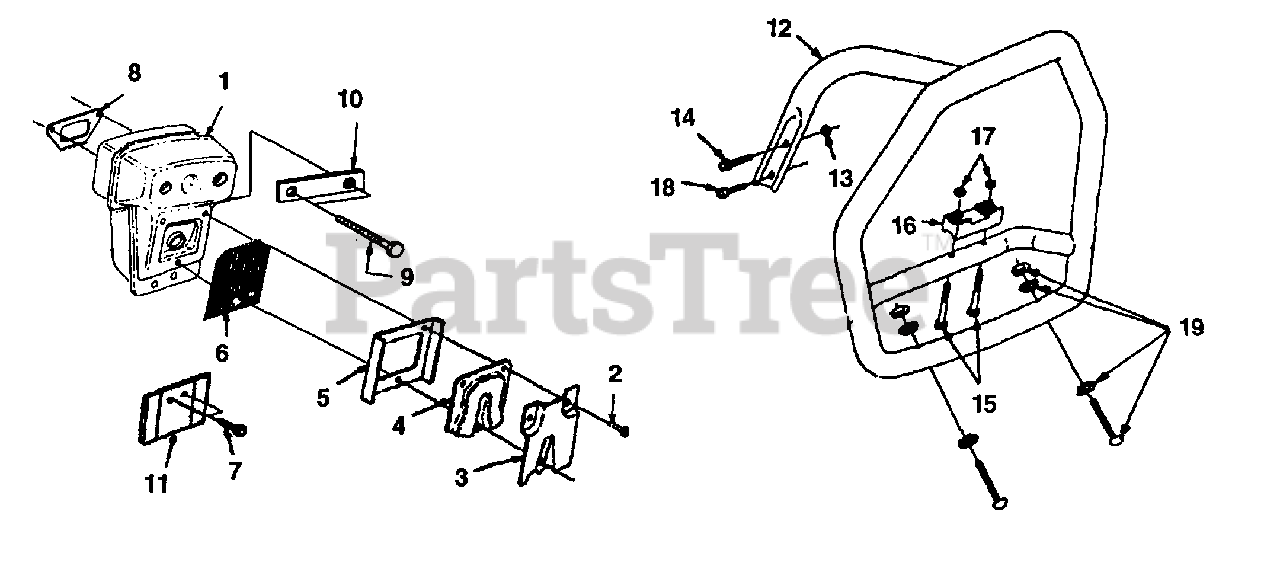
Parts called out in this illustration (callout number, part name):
1	MUFFLER ASSY
2	SCREW - Mach. Hex (8-32 X 1/2")
3	SHIELD - Muffler
4	CAP - Muffler
5	SUPPORT - Spark Arrestor
6	SCREEN - Spark Arrestor
7	SCREW - Truss Hd. (10-24 X 3/4")
8	GASKET - Muffler
9	SCREW - Cap Hex Hd (1/4-20 X 3 1/4")
10	SHIELD - Muffler Cover
11	PLATE - Retaining
12	HANDLE BAR
13	NUT - Hex Lock (10-24)
14	SCREW - Truss Hd. (10-24 X 3/4")
15	NUT - Locking (1/4-28")
16	BRACKET - Handle Bar
17	SCREW - Mach Oval Hd (1/4-20 X 1/2")
18	SCREW - Truss Torx (T25)
19	WEAR PAD KIT
